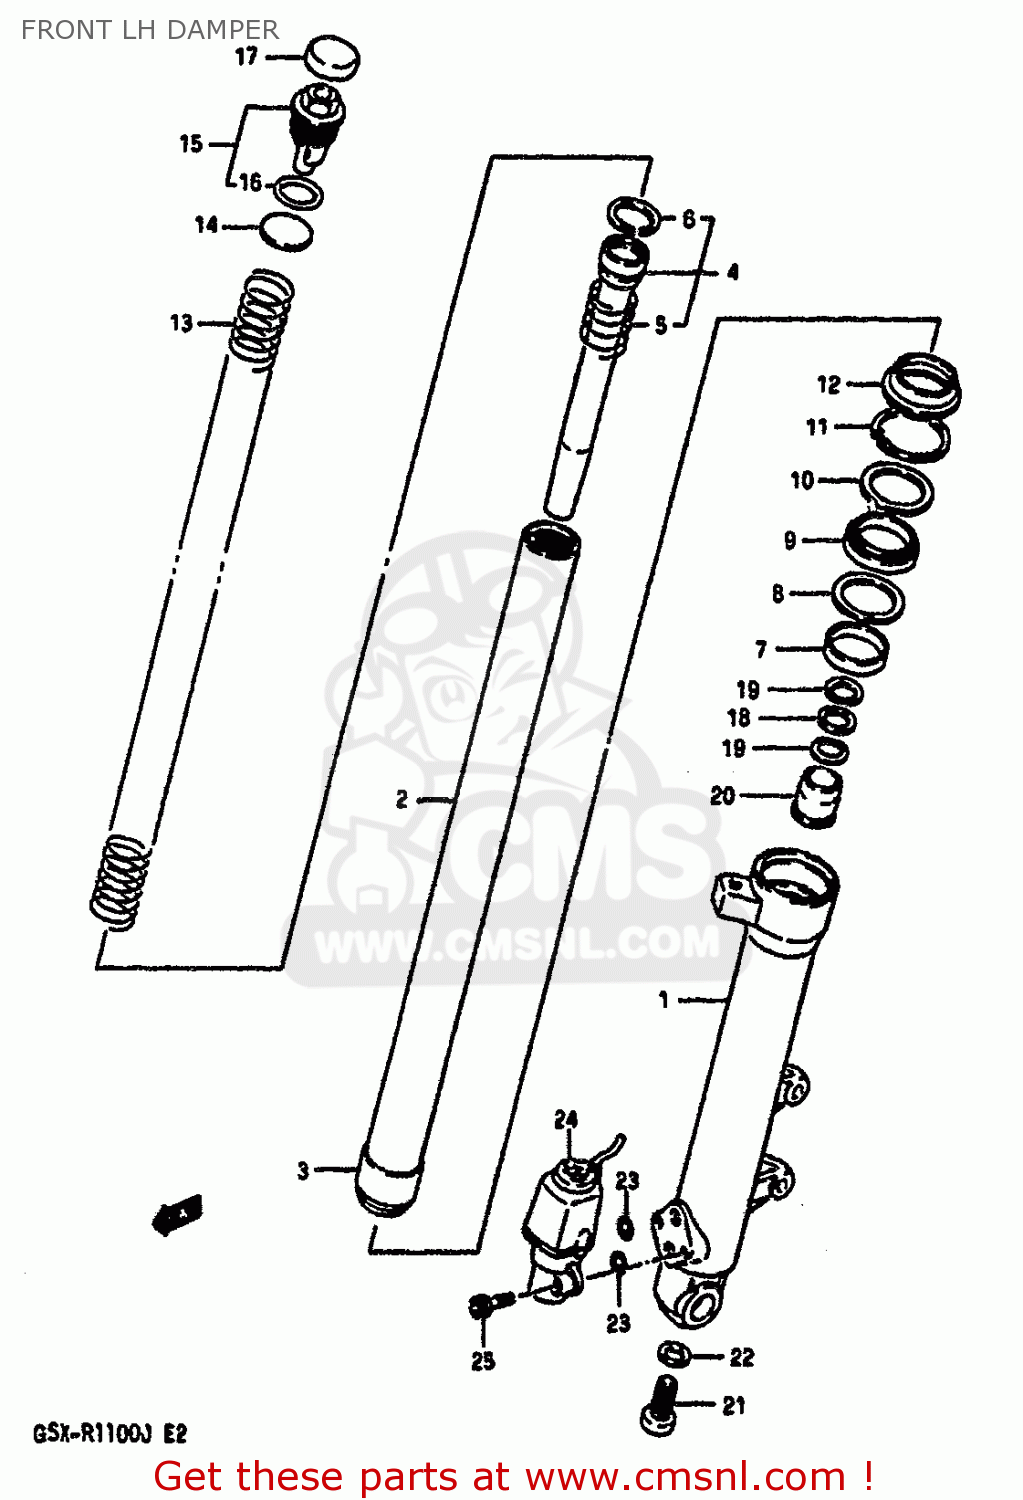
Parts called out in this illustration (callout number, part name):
1	TUBE,OUTER,LEFT
2	TUBE,INNER
3	METAL,SLIDE FR FORK
4	CYLINDER
5	SPRING,REBOUND
6	RING,FR FORK PISTON
7	METAL,SLIDE
8	WASHER,FORK OIL SEAL
9	OIL SEAL,FRONT FORK
10	WASHER,FORK OIL SEAL
11	RING,OIL SEAL STOPPER
12	DUST SEAL,FRONT FORK
13	SPRING
14	WASHER,FR FORK SPRING
15	CAP,FORK INNER TUBE
16	O RING
17	CAP,FORK INNER TUBE
18	WASHER,OIL LOCK PIECE
19	SPRING,FORK OIL LOCK PIECE
20	PIECE,OIL LOCK
21	BOLT(14X25)
22	GASKET (NAS)
23	O RING
24	EAND ASSY
25	BOLT
